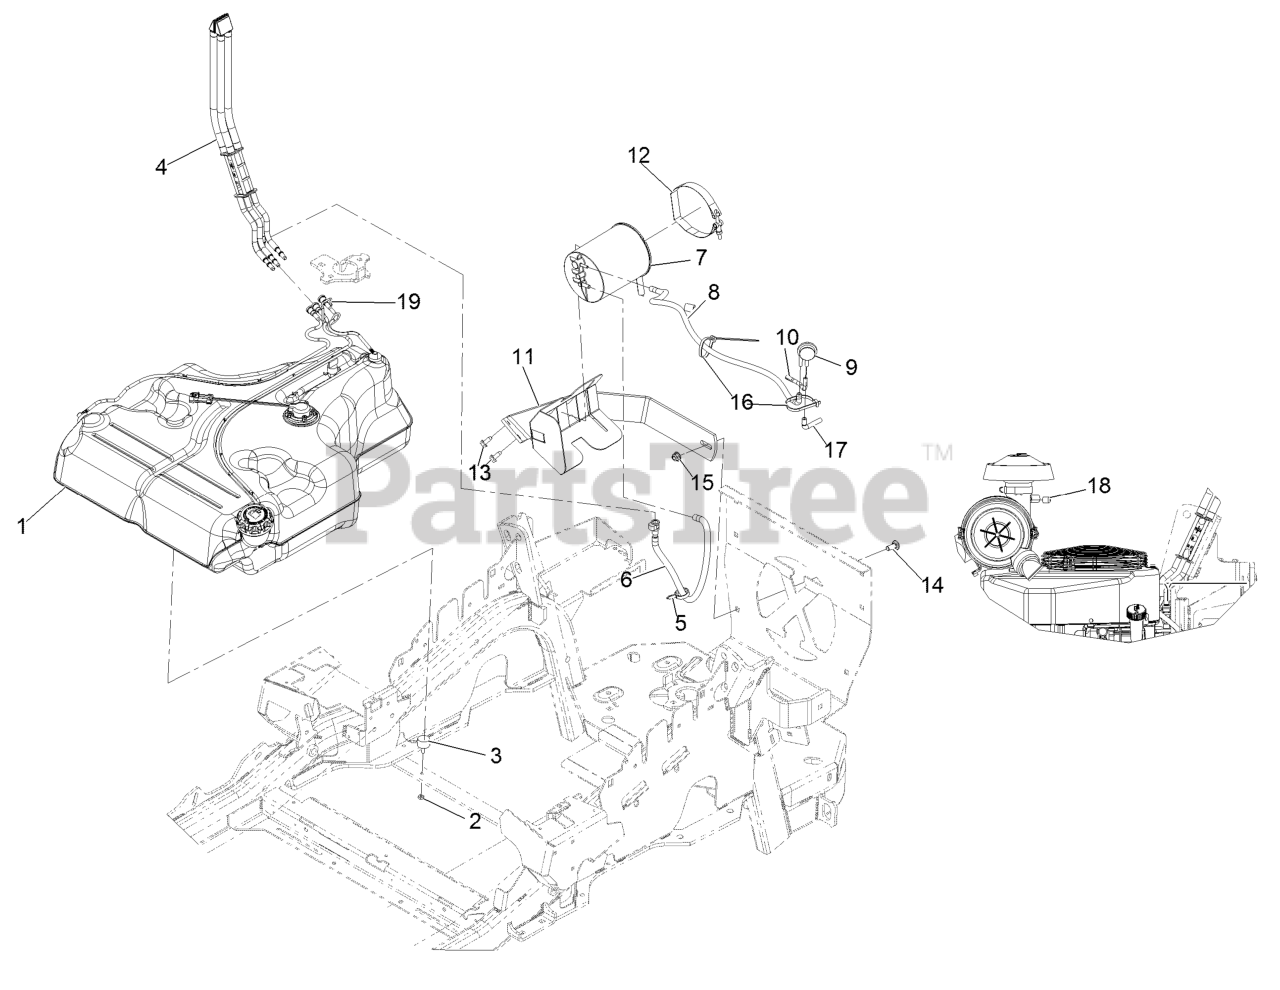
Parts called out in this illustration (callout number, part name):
2	NUT-JAM
4	FUEL MANIFOLD VENT ASM
5	CLAMP-HOSE
6	VENT HOSE ASM
7	CANISTER-CARBON, 1200CC
8	HOSE-VENT, FORMED
9	VALVE-CONTROL, VACUUM
10	HOSE-VENT, FORMED
11	MOUNT-CANISTER
12	CLAMP, T-BOLT
13	Screw-HWH 5/16-18 X 3/4 Tf
14	SCREW-CARR
15	NUT-HF, NI
16	TIE-PLASTIC
17	HOSE-VENT, FORMED
18	PLUG-PORT
19	RETAINER-LINE, VAPOR
